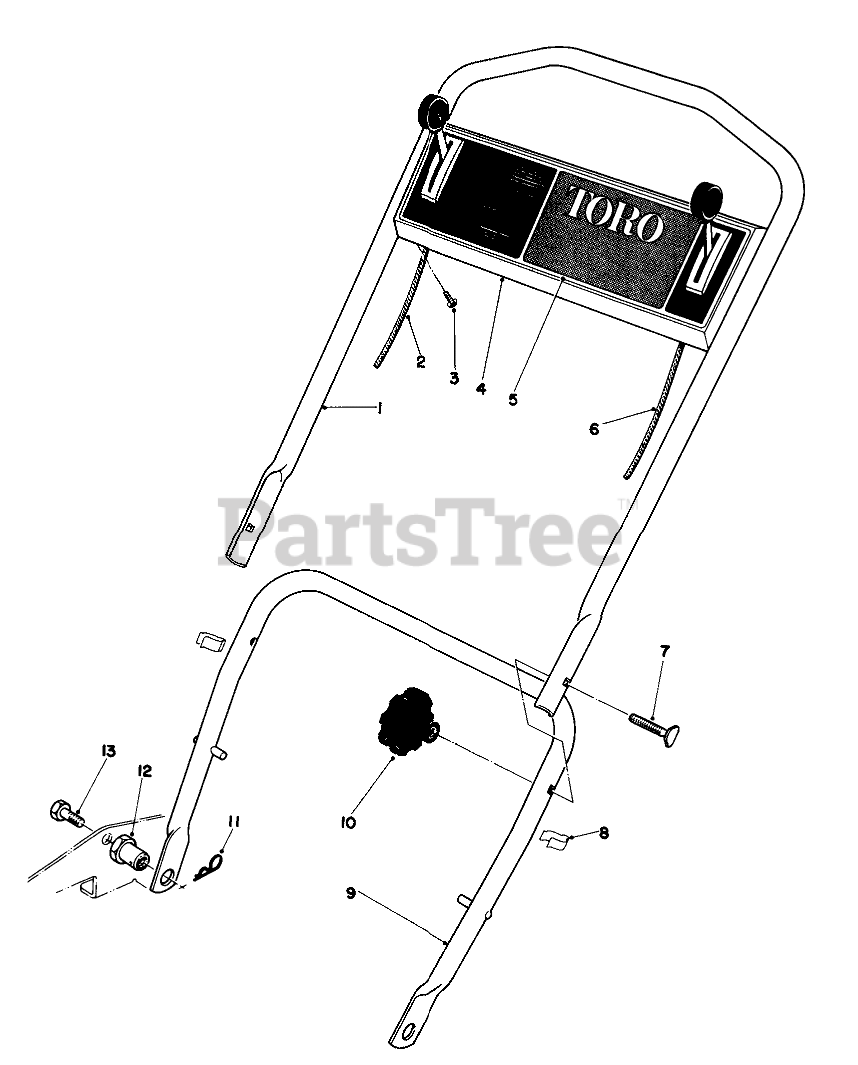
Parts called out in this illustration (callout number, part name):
1	UPPER HANDLE
2	Throttle Control
3	SCREW-HWHTF
4	Control Plate
5	Decal-Control Plate
6	Control-Traction
7	SCREW-HANDLE
9	LOWER HANDLE ASM
11	PIN-COTTER, HAIR
12	HANDLE PIVOT NUT
13	SCREW-HH
